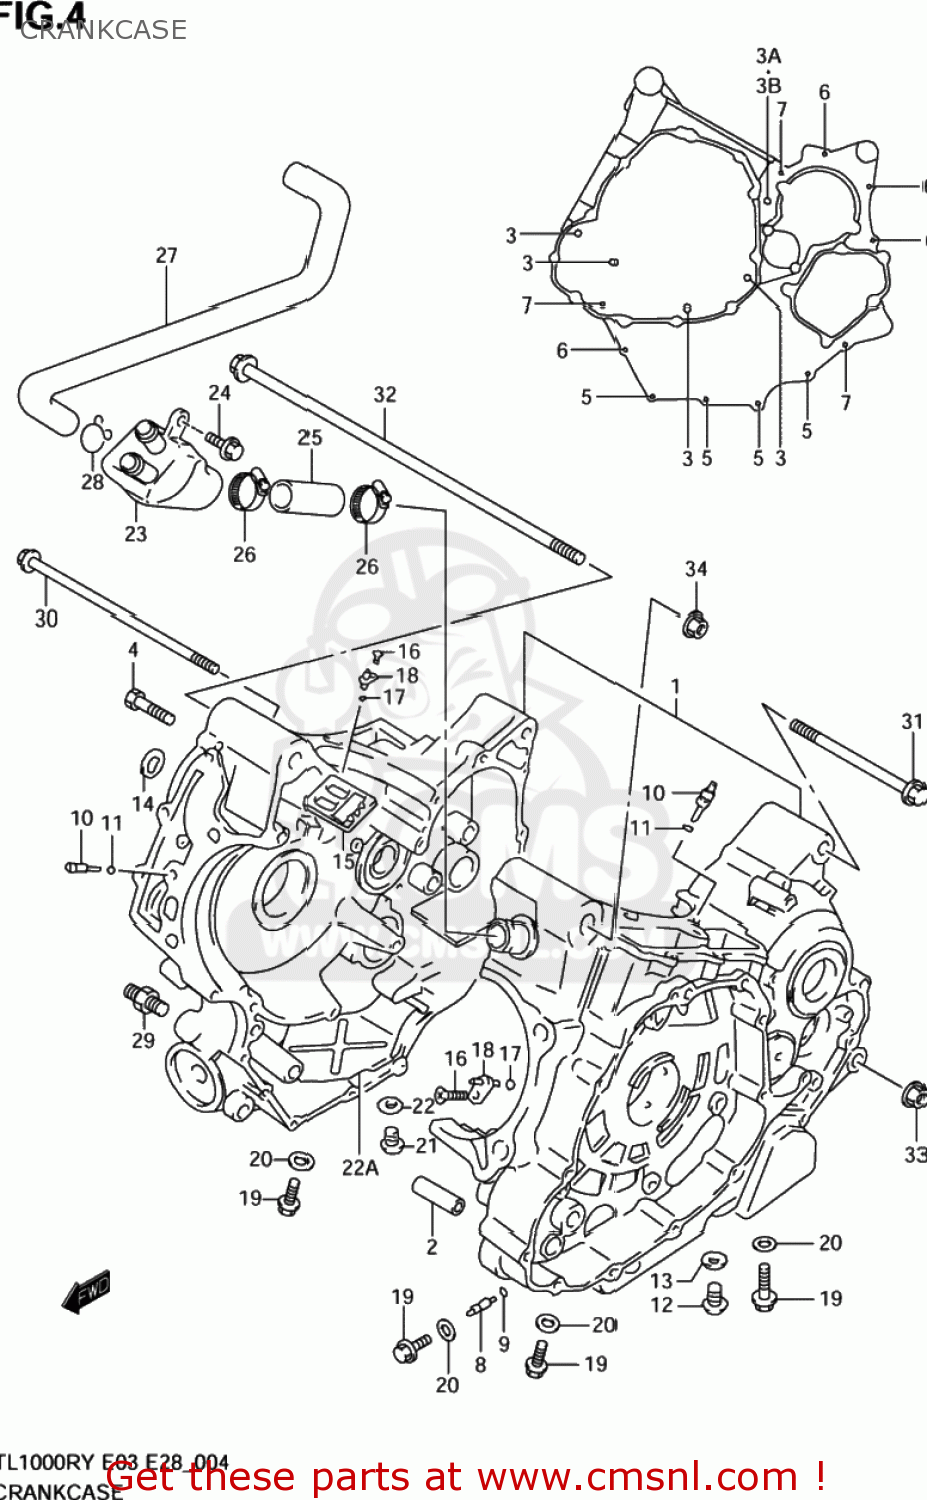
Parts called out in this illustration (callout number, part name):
1	CRANKCASE SET
2	PIN,CRANKCASE
3	BOLT
3A	BOLT(8X125)
3B	WASHER
4	BOLT(8X110)
5	BOLT
6	BOLT
7	BOLT
8	JET,AIR(14)
9	O RING(D:1.2,ID:4)
10	JET,OIL GALLERY
11	O RING(D:1.2,ID:4)
12	PLUG
13	GASKET(13.8X18.8X4.8) (NAS)
14	O RING(D:1.9,ID:12.6)
15	VALVE ASSY,BREATHER
16	SCREW(6X12)
17	O RING(D:1.2,ID:4)
18	JET,PISTON COOLING
19	BOLT
20	GASKET(8.2X14X1).6 (NAS)
21	PLUG,16X8
22	GASKET(16X22X2) (NAS)
22A	SEPARATOR,OIL
23	TANK,OIL RETURN
24	BOLT
25	HOSE, OIL RETU
26	CLAMP
27	HOSE,BREATHER
28	CLIP
29	SWITCH ASSY,OIL PRESSURE
30	BOLT(10X205)
31	BOLT(10X155)
32	BOLT(12X200)
33	NUT
34	NUT
